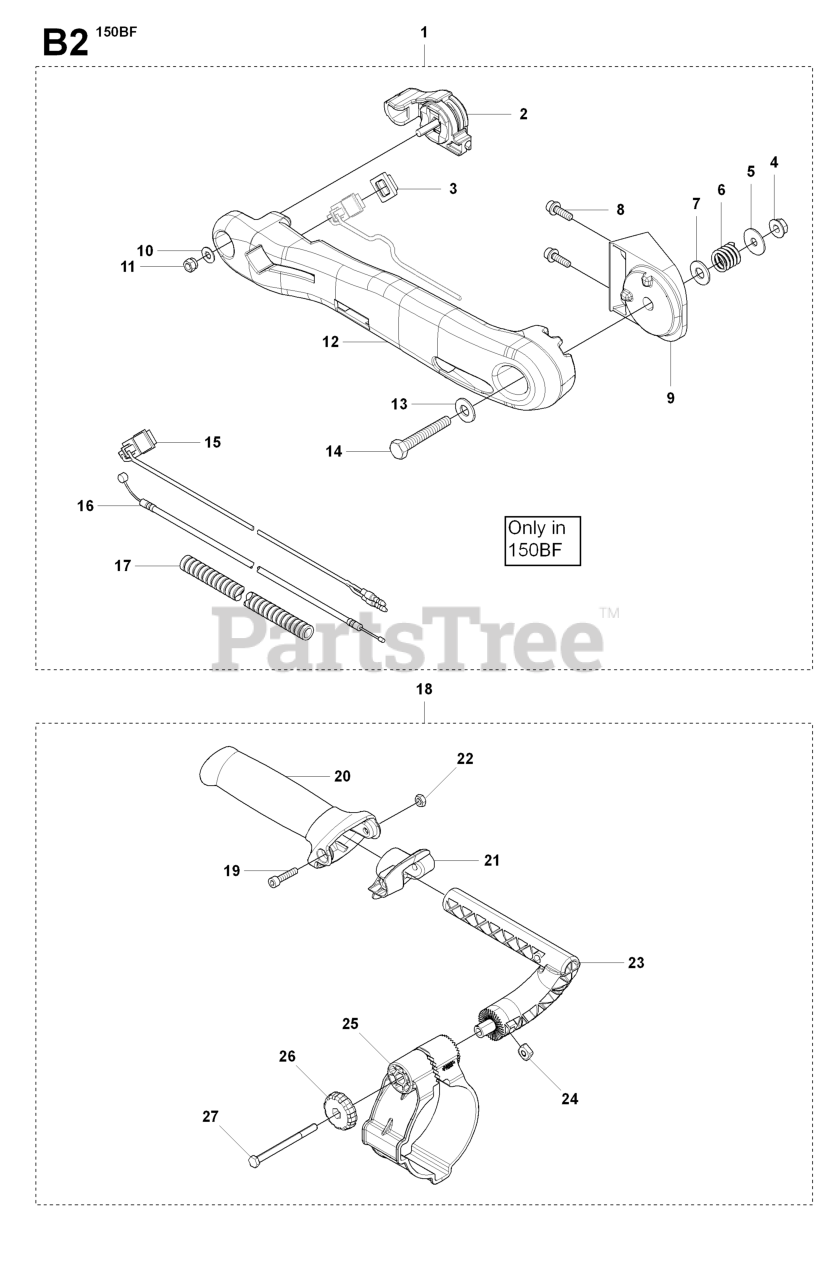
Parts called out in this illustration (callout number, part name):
1	HANDLE ASSY
2	LEVER
3	CAP
4	NUT
5	WASHER
6	SPRING
7	WASHER
8	SCREW
9	RP_BRACKET
11	NUT
12	ARM
13	WASHER
14	BOLT
15	KILL SWITCH
16	CABLE COMP
19	SCREW
23	BRACKET
25	HOLDER TH
